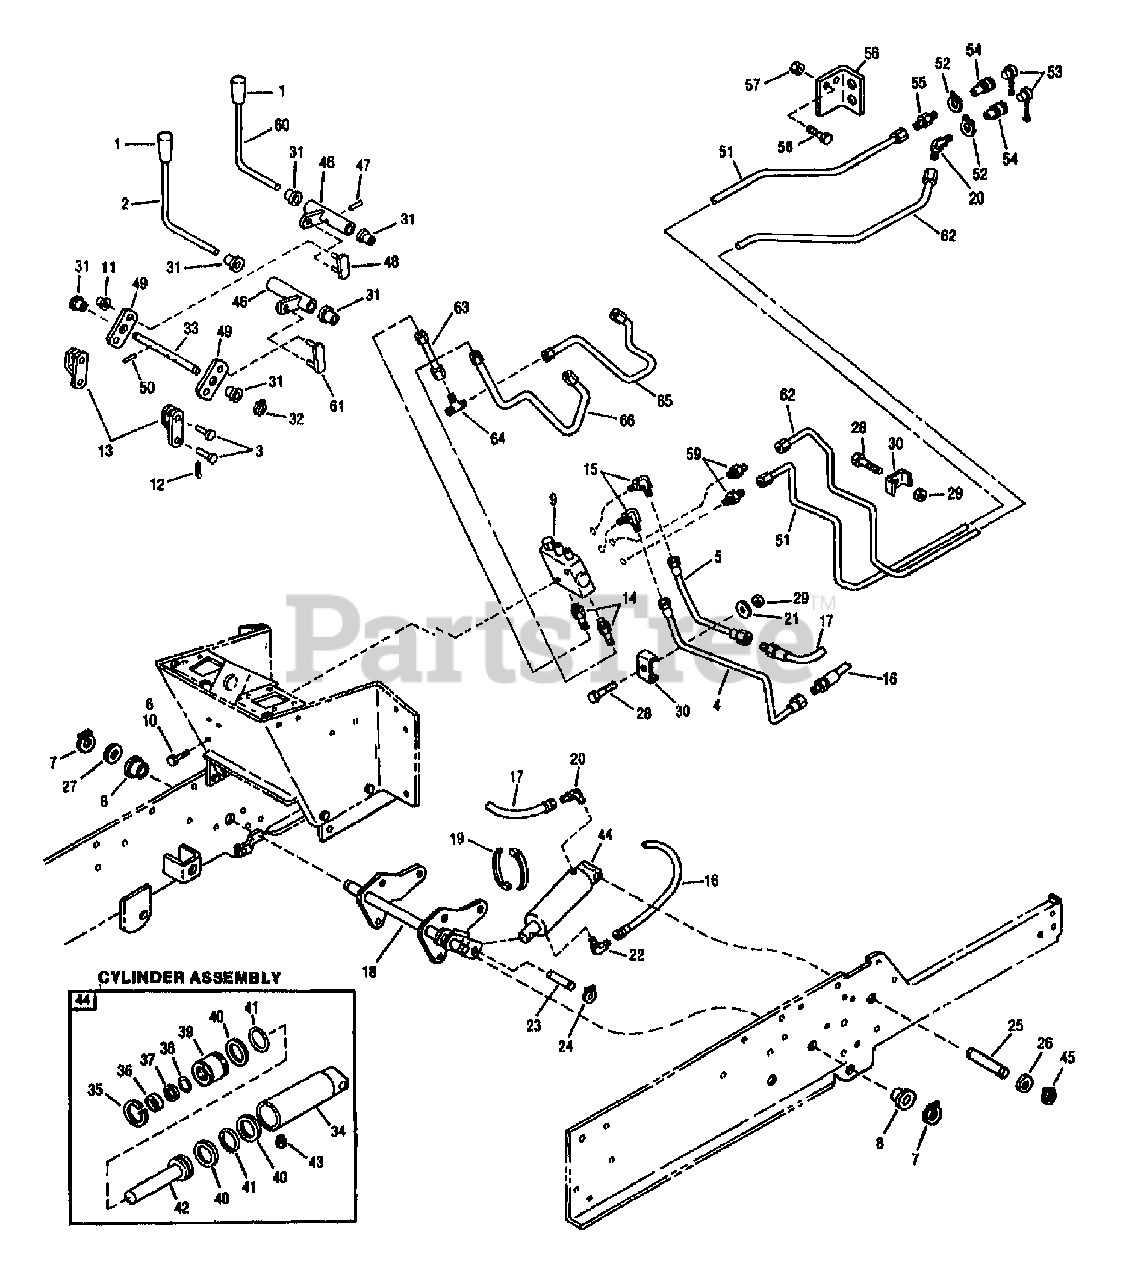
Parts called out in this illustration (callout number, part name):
1	KNOB-SHIFT LEVER
2	LEVER-CONTROL
3	PIN-CLEVIS .25X.81
4	ASSM-TUBE
5	ASSM-TUBE
6	SCR-HFLK 1/4-20X2.00 G5ZP
7	RING-RETAINING
8	BUSHING-FLANGE
10	NUT-HF/LK 1/4-20 ZP
11	NUT-PUSH
12	PIN-COTTER
13	ASSM-VALVE LINK
14	CONNECTOR
15	ELBOW
16	ASSM-HOSE
17	ASSM-HOSE
18	SHAFT-LIFT
19	TIE-CABLE NYLON BLACK
20	ELBOW
21	WASHER-FLAT 1.25X.406X.179
22	ELBOW
24	RING-RETAIN .625 ID
26	WASHER-1.5X.755X.062
27	WASHER-SPEC
28	SCR-HH 5/16-18X1.0 G5 ZP
29	NUT-TOP/LK 5/16-18 ZP
30	CLAMP
31	BRG-FLANGE
32	RING-RETAINING
33	PIN-PIVOT
34	ASSM-CYL HYDRAULIC
35	RING-RETAIN INT 2.210 DIA
36	SEAL-OIL
37	RING-BACK/UP
38	RING-O .984 ID
39	HEAD-CYLINDER
40	RING-BACK/UP
41	RING-O 1.6 ID
42	ASSM-ROD HYDR CYLINDER
43	PLUG-PIPE
44	ASSM-CYL HYDRAULIC
45	RING-RETAIN EXT .707 ID
46	ASSM-CONTROL ARM
47	PIN-DRIVE
48	ASSM-CONTROL LINK
49	ARM-ROCKER
50	PIN-ROLL .125 X .62
51	ASSM-TUBE LOWER VALVE
52	RING-RET. EXT .875 ID
53	PLUG-DUST
54	COUPLING-BODY
55	CONNECTOR
56	BRKT-COUPLING
57	NUT-HFLK 3/8-16 ZP
58	SCR-HFLK 3/8-16X1.00 ZP
59	CONNECTOR
60	LEVER-CONTROL
62	ASSM-TUBE UPPER VALVE
63	ASSM-TUBE
65	ASSM-TUBE
66	ASSM-TUBE
